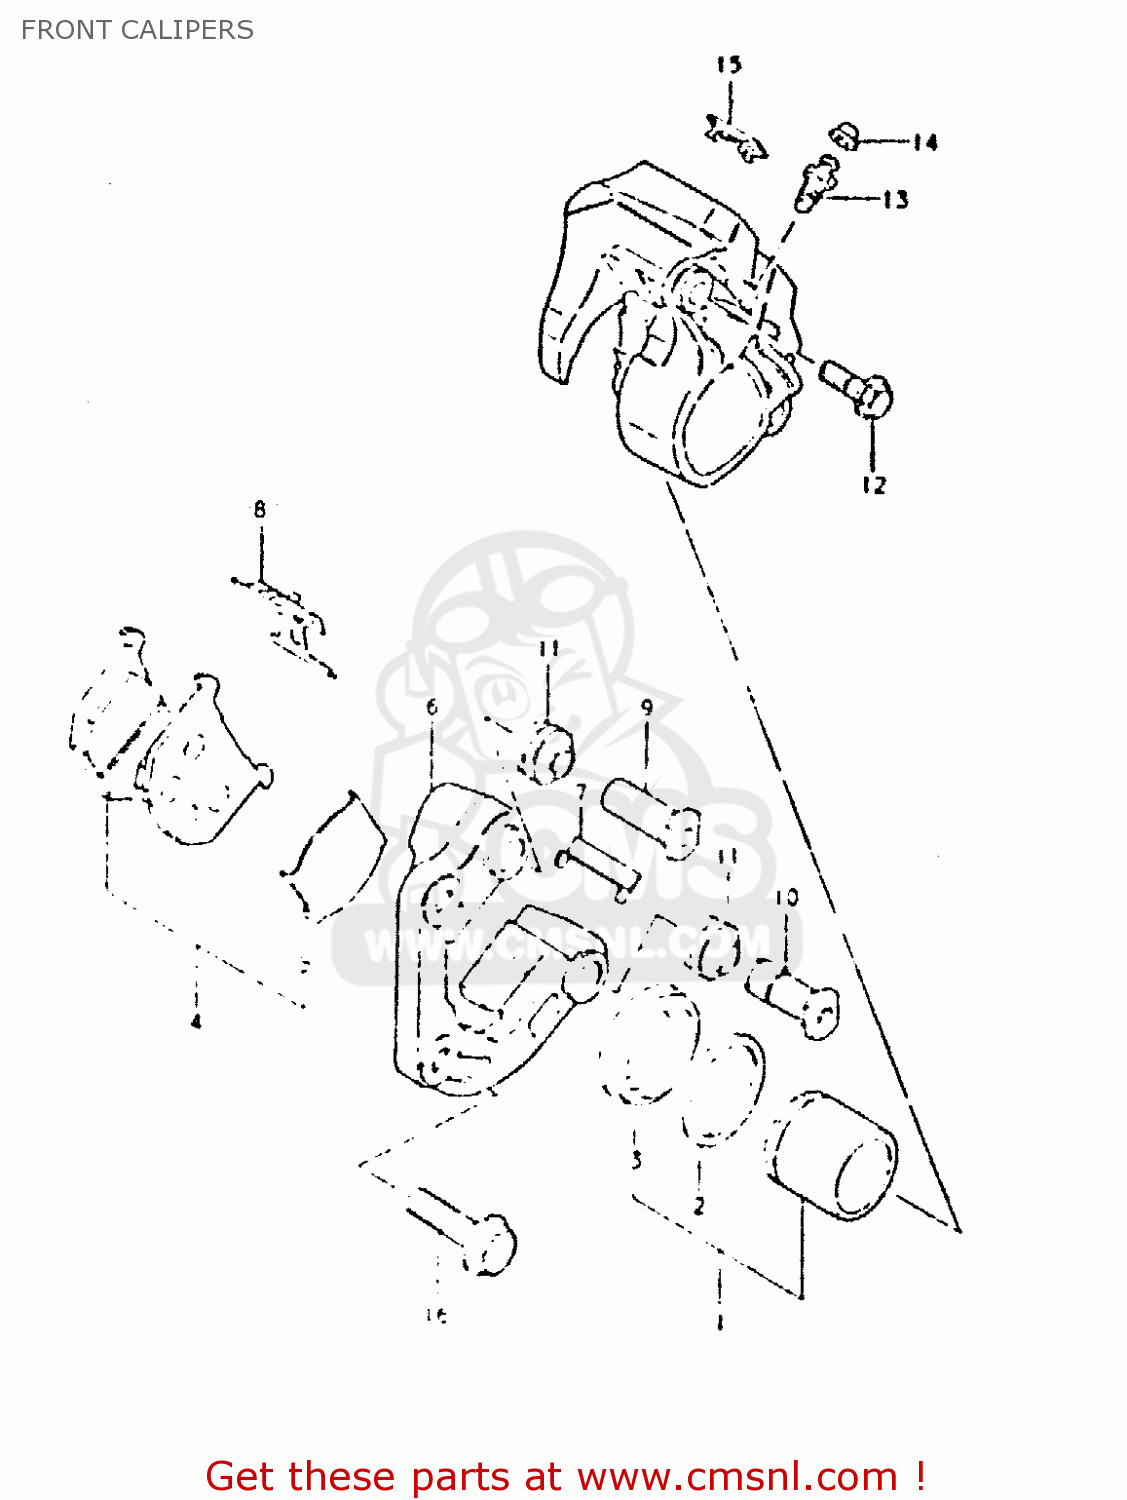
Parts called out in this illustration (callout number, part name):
1	PISTON SET
2	SEAL,FR CALIPE
3	BOOT,PISTON
4	PAD SET (MCA)
5	SHIM,PAD
6	CARRIER,CALIPER,LEFT
7	GUIDE,PAD
8	SPRING,PAD
9	AXLE NO.1
10	AXLE NO.2
11	BOOT,AXLE
12	BOLT,CALIPER HOUSING
13	BLEEDER
14	CAP,BREATHER
15	COVER,INDICATOR
16	BOLT(10X37)
